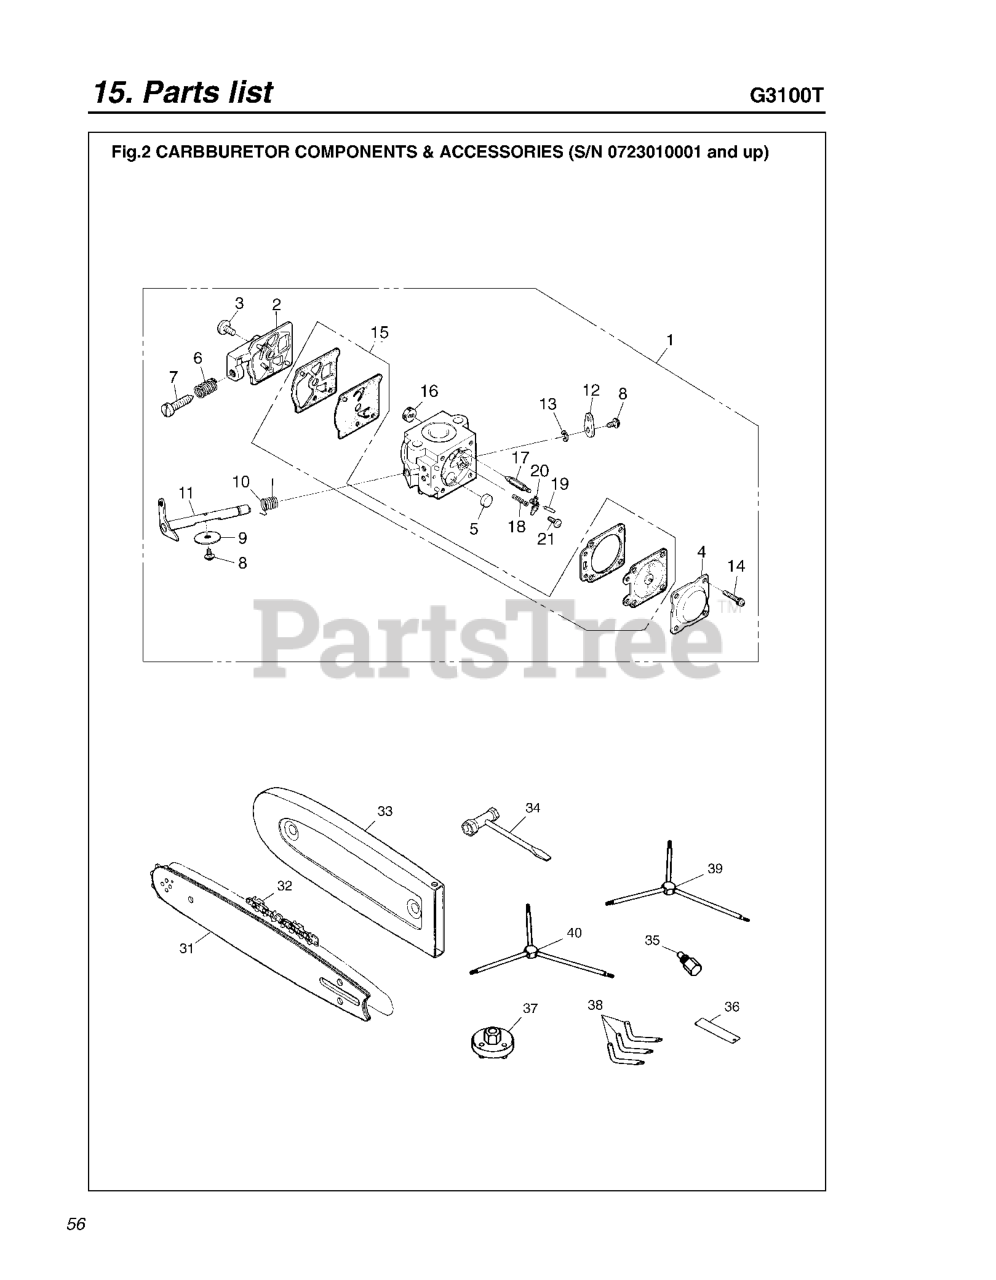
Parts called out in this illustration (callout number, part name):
1	CARBURETOR ASSY
8	SCREW
10	SPRING RETURN
14	SCREW ASSY
15	CARBURETOR DIAPHRAGM/GASKET KI
15	RedMax TBD
16	SCREEN
17	VALVE INLET
33	PROTECTOR
